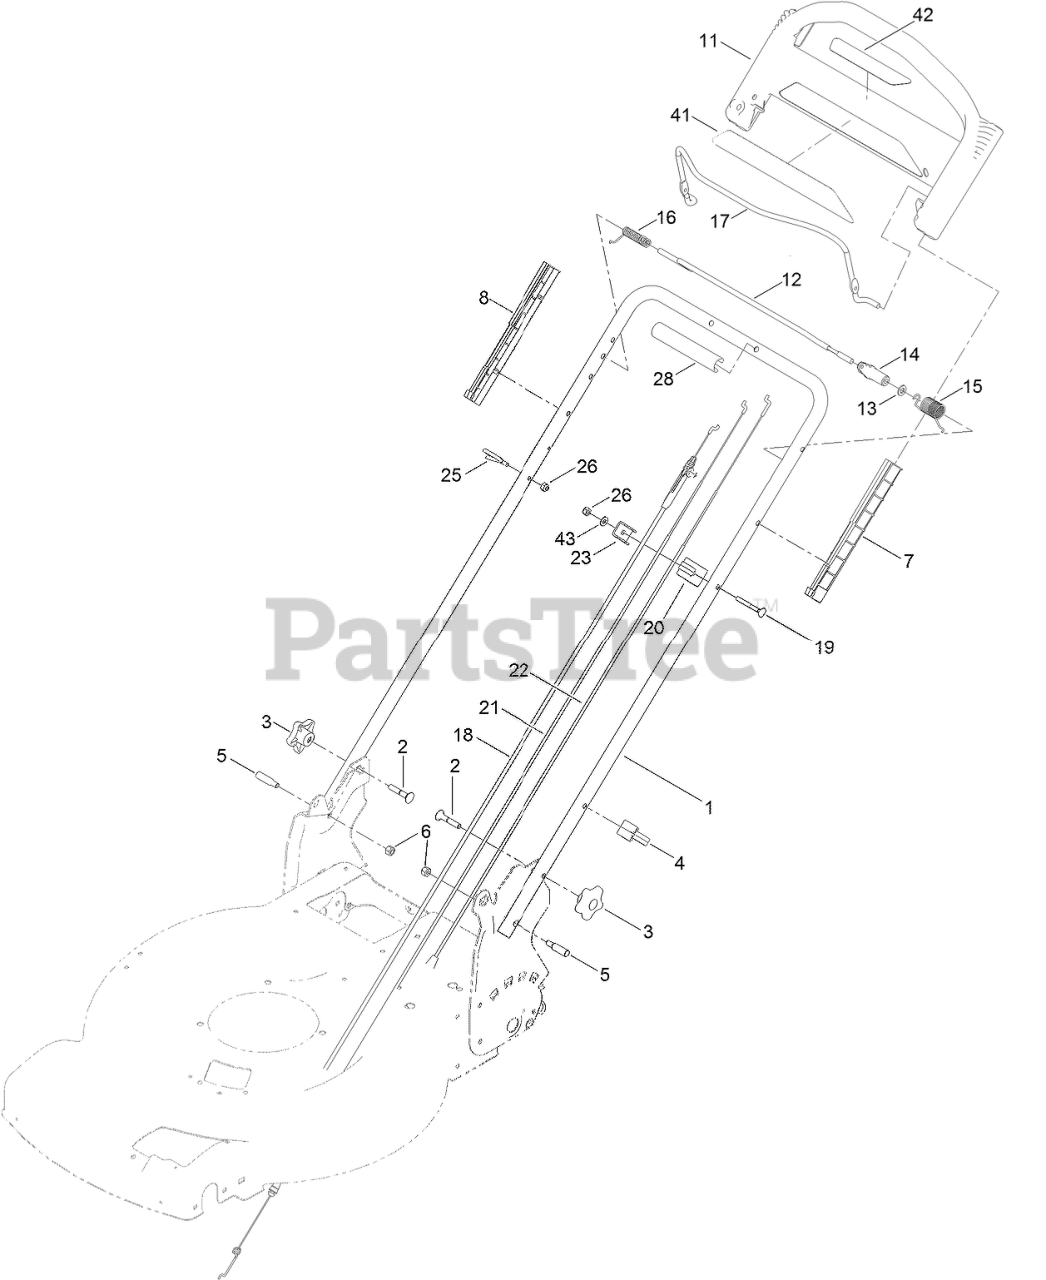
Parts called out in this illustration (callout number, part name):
2	SCREW-CARR
3	KNOB-HANDLE
4	GUIDE-CABLE
5	BOLT-SHOULDER
6	NUT-HEX
7	GUIDE-LH
8	GUIDE-RH
11	HANDLE-PACE, PERSONAL
12	BAR-CONTROL, TRACTION
13	WASHER-PLAIN
14	LEVER-TRACTION
15	SPRING-TORSION
16	SPRING-TORSION
17	BAIL-BRAKE
18	CABLE-BRAKE
19	SCREW-HANDLE
20	MOUNT-CABLE, TRACTION
21	CABLE-TRACTION, FRONT
22	CABLE-TRACTION, REAR
23	CLAMP-CABLE
25	GUIDE-ROPE
26	NUT-HEX
28	HANDLE-COVER
41	DECAL-POWEREVERSE
42	DECAL-INSTRUCTION, DRIVE
43	WASHER-FLAT
